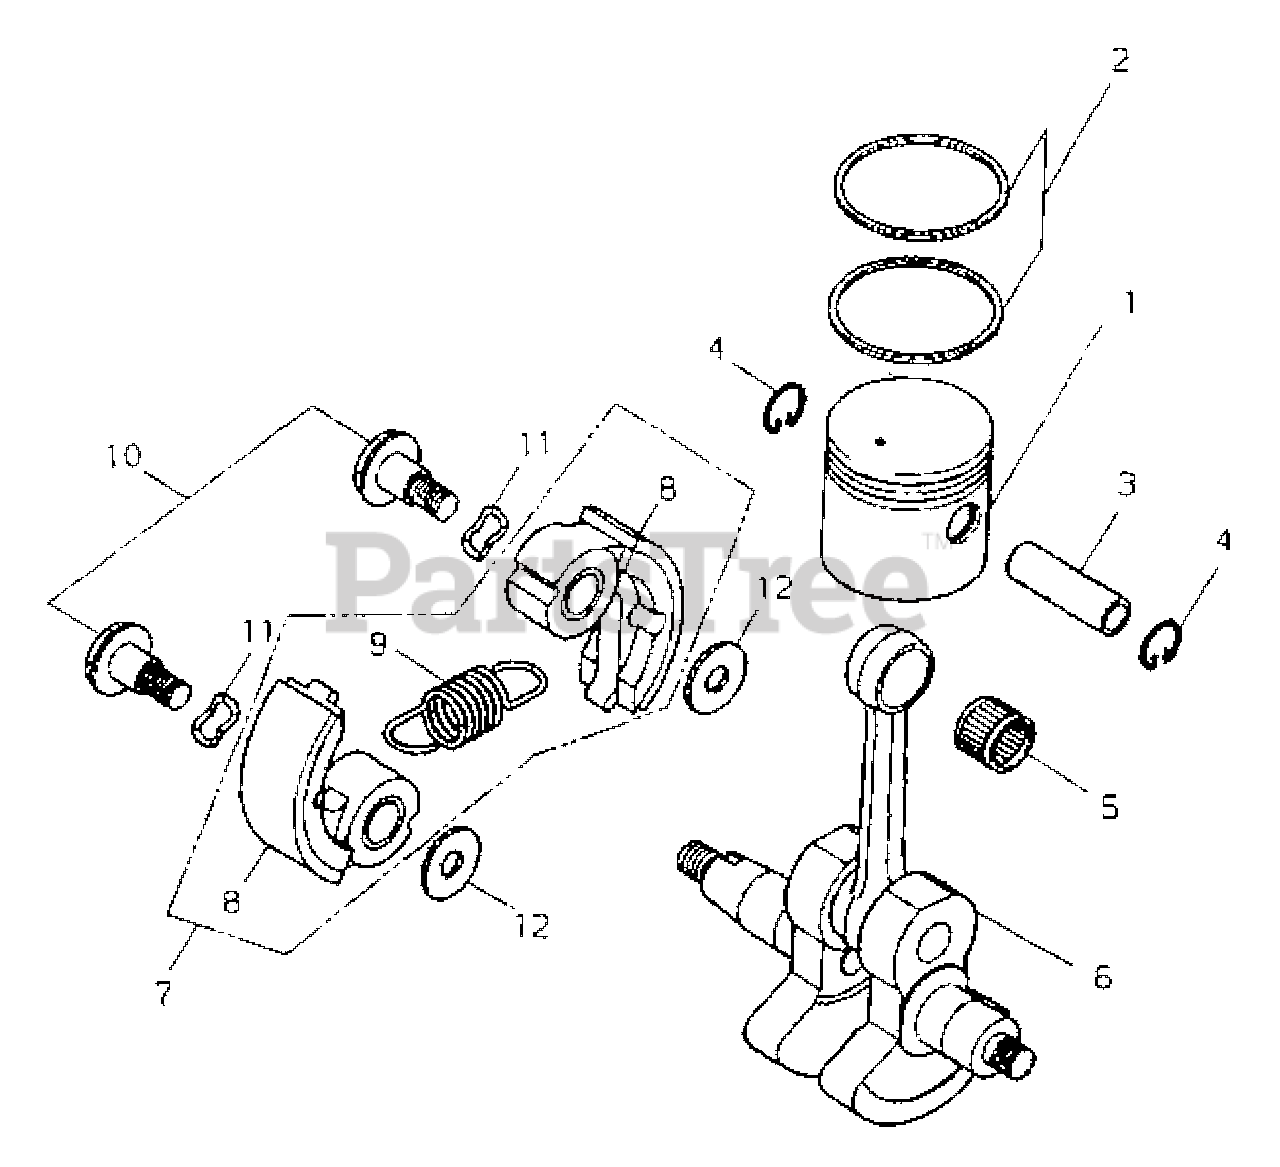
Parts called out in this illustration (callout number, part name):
1	PISTON
2	RING, PISTON
3	PIN, PISTON
4	RING, RETAINING
5	BEARING, NEEDLE
6	CRANKSHAFT ASSY
7	CLUTCH SHOE ASSY
8	SHOE, CLUTCH
9	SPRING
10	BOLT, CLUTCH
11	PLATE, SPRING
12	WASHER
